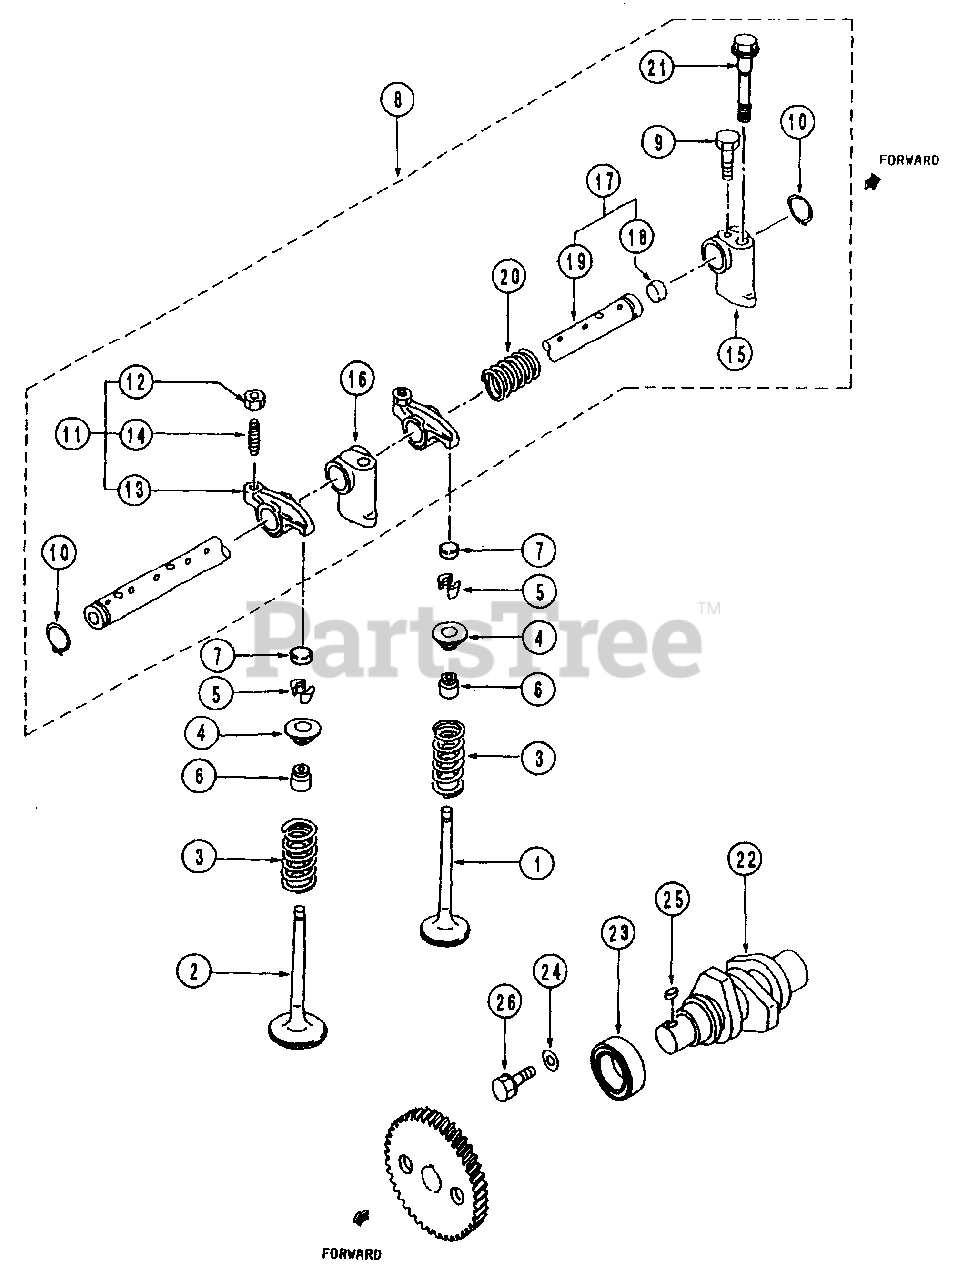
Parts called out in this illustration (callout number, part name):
1	Valve, Inlet
2	Valve, Exhaust
3	Spring, Valve
4	Retainer
5	Valve, Lock
6	Seal, Valve Stem
8	Rocker & Shaft Ass'y.
11	Rocker Ass'y.
13	Rocker
14	Screw, Rocker
15	Bracket, Rocker Shaft
16	Bracket, Rocker Shaft
18	Cap, Sealing
19	Shaft, Rocker
20	Spring, Rocker
21	Bolt, Rocker Bracket
22	Shaft, Fuel Inj. Pump
23	Bearing, Ball
26	Bolt, W/Washer
